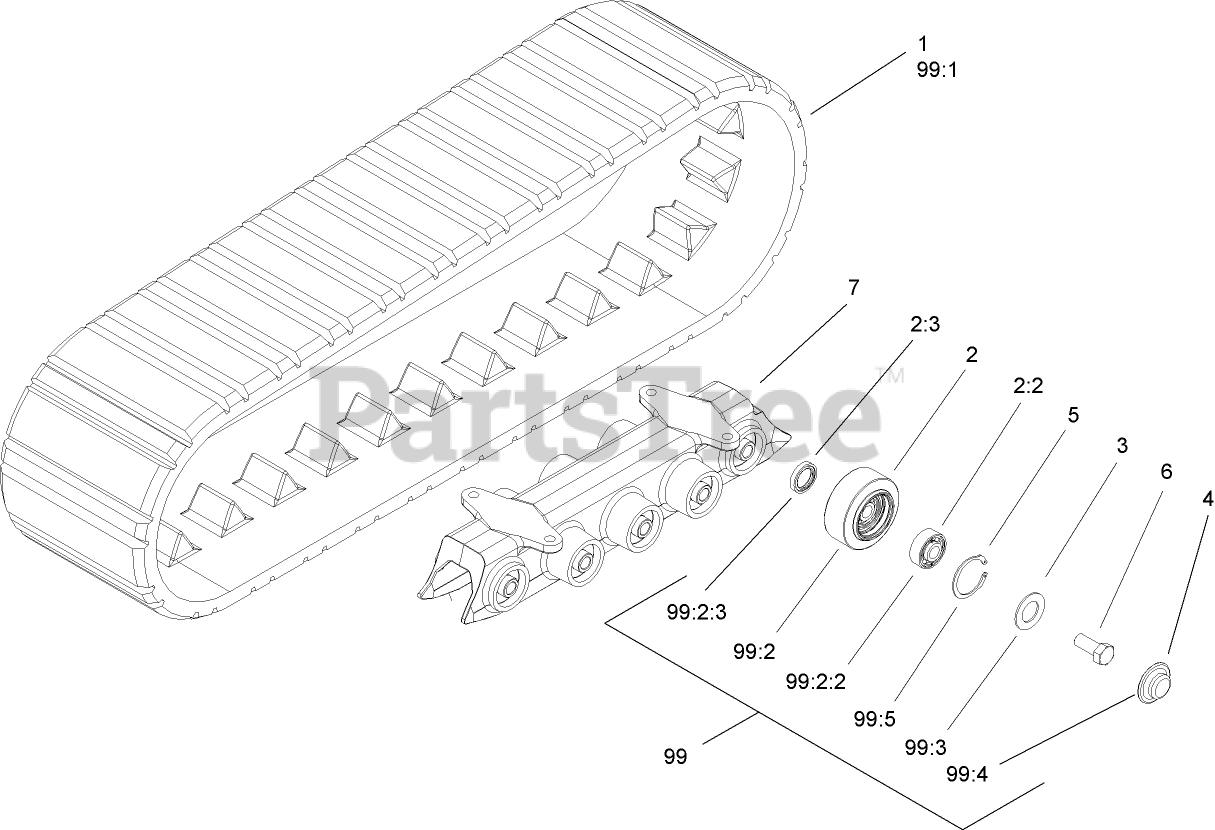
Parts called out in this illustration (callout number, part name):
1	TRACK
2	Road Wheel ASM
2:2	BEARING
2:3	SEAL-OIL
3	Gasket-Bogie
4	CAP-WHEEL, BEARING
5	RING-SNAP, INTERNAL
6	SCREW-HH
7	GUIDE-TRACK
99	TRACK REBUILD KIT
99:1	TRACK
99:2	Road Wheel ASM
99:2:2	BEARING
99:2:3	SEAL-OIL
99:3	Gasket-Bogie
99:4	CAP-WHEEL, BEARING
99:5	RING-SNAP, INTERNAL
